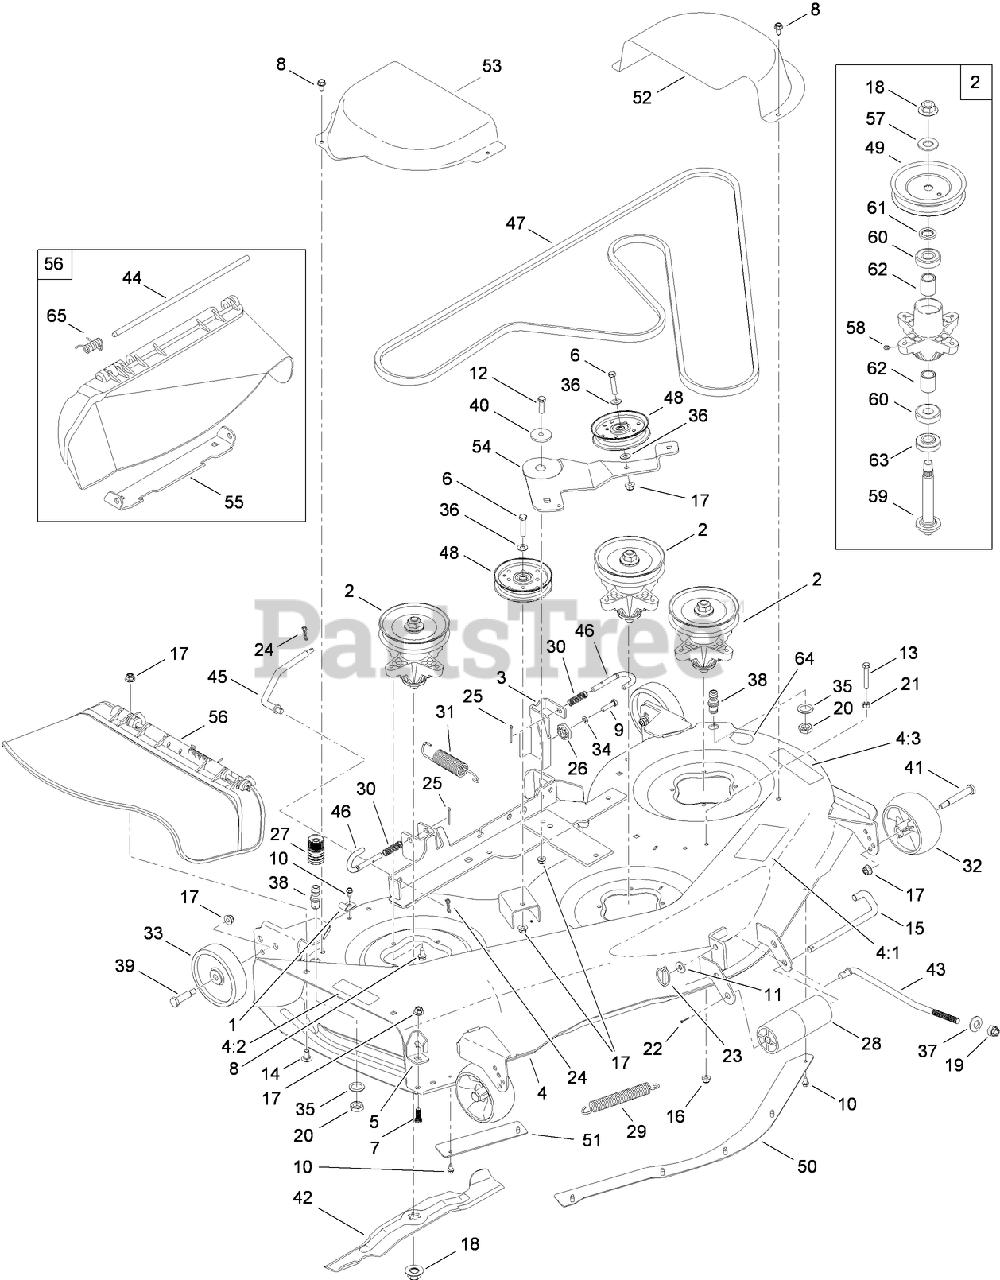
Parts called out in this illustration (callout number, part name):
1	BRACKET-RETAIN, HOOK
2	SPINDLE ASM
3	LH HANGER BRACKET ASM
4	50 INCH DECK ASM
4:1	DECAL-BELT ROUTING, DECK
4:2	DECAL-CHUTE
4:3	DECAL-DECK
5	STOP-CHUTE
6	SCREW-HH
7	SCREW-HH
8	SCREW-TAP
9	SCREW-HH
10	SCREW-HWHTF
11	WASHER-FLAT
12	SCREW-HH
13	SCREW-HH
14	BOLT-CARR
15	PIN-ROLLER
16	NUT-LOCK, FLANGE
17	NUT-LOCK, FLANGE
18	NUT-LOCK, FLANGE
20	NUT-HEX
21	NUT-HEX
22	PIN-COTTER
23	PIN-LYNCH
24	PIN-COTTER
25	PIN-COTTER
26	GEAR-ADJUSTMENT, DECK
27	ADAPTER-NOZZLE, WATER
28	ROLLER-FRONT
29	SPRING-EXTENSION
30	SPRING-COMPRESSION
31	SPRING-LIFT, ASSIST
32	WHEEL-DECK, FRONT
33	WHEEL-DECK, REAR
34	WASHER-LOCK
35	WASHER-LOCK
36	WASHER-FLAT
37	WASHER-BELLVILLE
38	NOZZLE-WATER, DECK
39	BOLT-SHOULDER
40	SPACER-SHOULDER
41	BOLT-SHOULDER
43	ROD-DECK LIFT, FRONT
44	PIN-HINGE
45	ROD-DECK SWAY
46	PIN-HANDLE, DECK RELEASE
47	BELT-V TYPE
48	PULLEY-IDLER
49	PULLEY
50	SKIRT-CENTER
51	SKIRT-RH
52	COVER-BELT, LH
53	COVER-BELT, RH
54	BRACKET-IDLER
55	BRACKET-CHUTE
56	CHUTE ASM
57	WASHER-FLAT
58	FITTING-GREASE
59	SHAFT-SPINDLE, BLADE (STAR)
60	BEARING-BALL
61	SPACER
62	SPACER
63	SPACER
64	DECAL-DECK WASH SYSTEM
65	SPRING-TORSION
